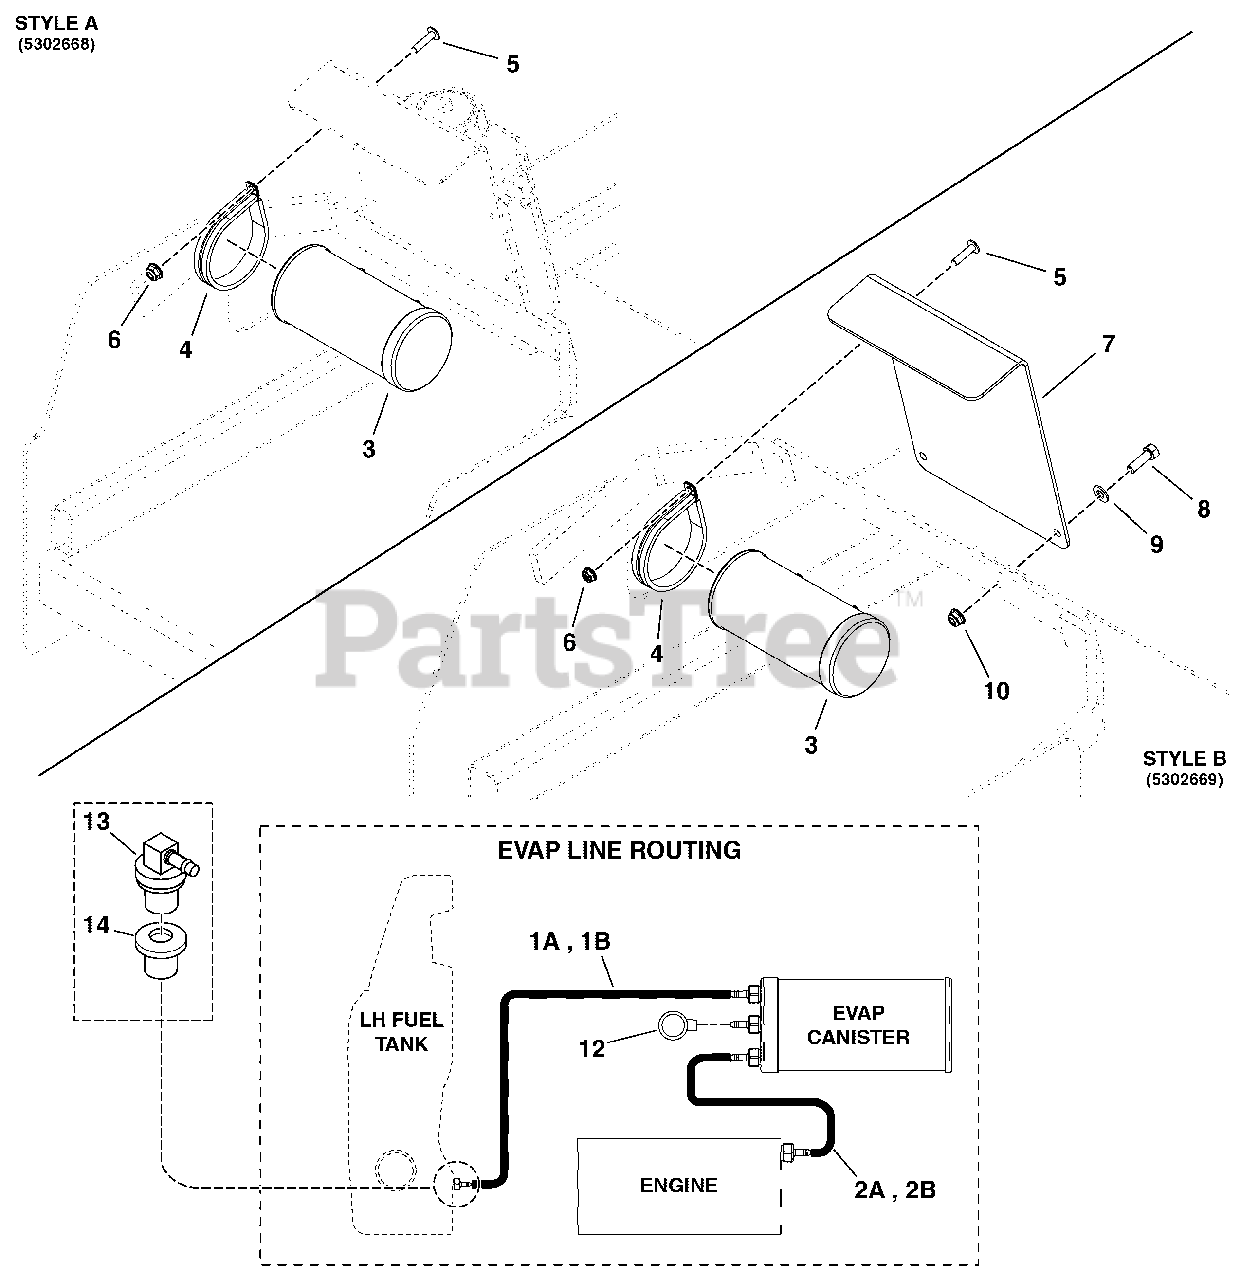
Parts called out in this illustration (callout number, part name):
3	CNSTR, CARB, 6 GAL
4	CLAMP, 3" ID, CUSHIONED, STAINLESS
6	NUT, 1/4-20 HEX NYLOCK FLANGE
7	PLATE, CARB CANISTER MOUNT, IS1500 - BLK
8	BOLT, 5/16-18 X 1 GD5 YZ
9	WASHER, 5/16" SAE
10	NUT, 5/16-18 HEX NYLOCK FLANGE
11	DECAL, EPA CERT, ZTRS
12	DUST FILTER, CANISTER (SV)
13	REMOTE VENT ASSEMBLY
14	GROMMET
